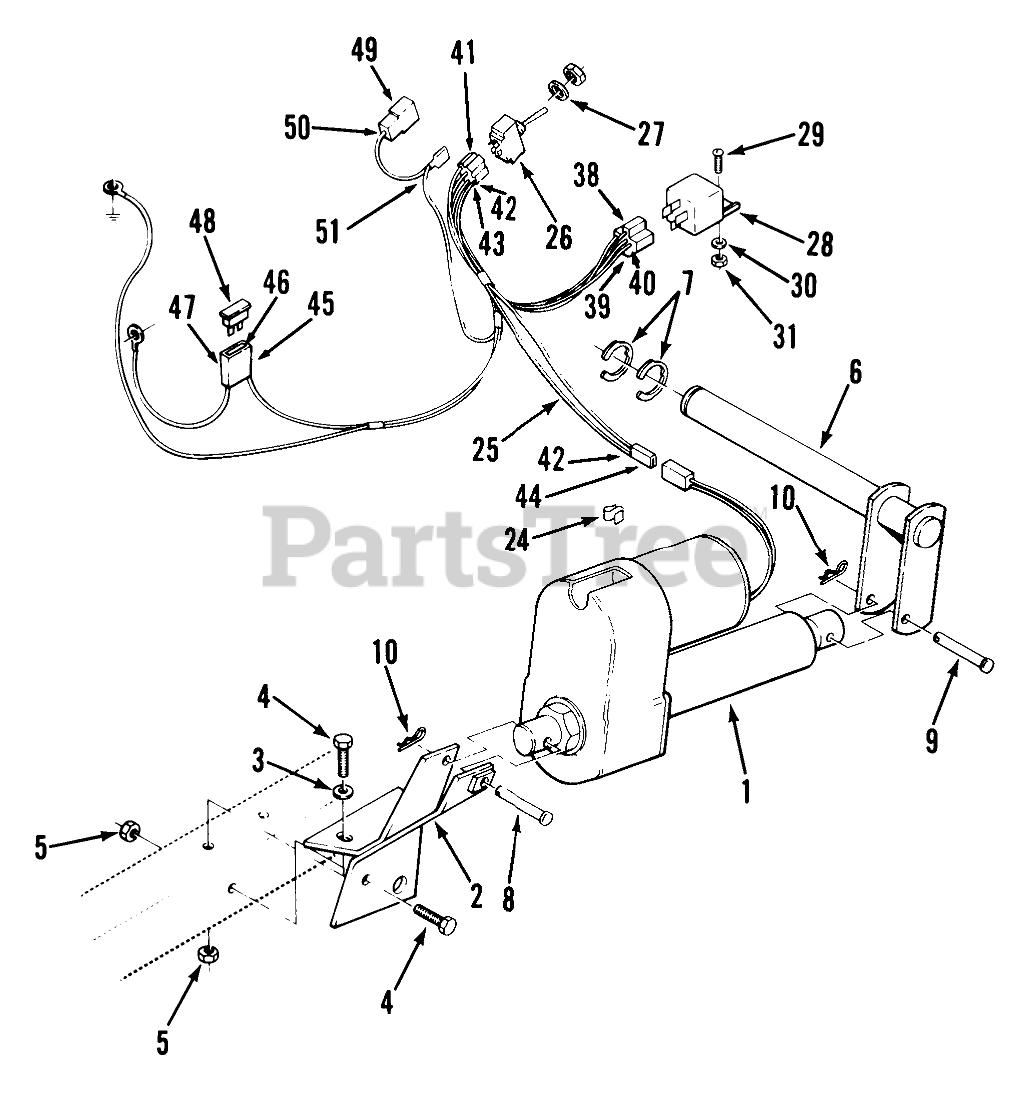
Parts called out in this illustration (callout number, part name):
1	Linear Actuator
2	Lift Bracket
3	Washer
4	BOLT
5	Nut
6	ASSY LIFT ARM B
7	Retainer
8	Clevis Pin 1/2 x 2 3/4
9	CLEVIS PIN
10	Hairpin Cotter
24	SPEED CLIP
25	WIRING HARNESS
26	SWITCH
27	Washer
28	RELAY
29	Screw
30	Washer
31	Nut
38	Connector Body (Part of Item 10)
39	Female Terminal (Part of Item 10)
40	TERMINAL FEMALE
41	CONNECTOR 5 WAY
42	Terminal
43	TERMINAL-TAB RCPT
44	CONNECTOR BODY B
45	AUTO-FUSEBLOCK TERM
46	TERMINAL FUSE
48	FUSE-BLADE, 25 AMP
49	Connector Body
50	Connector Part of 5
51	Terminal
